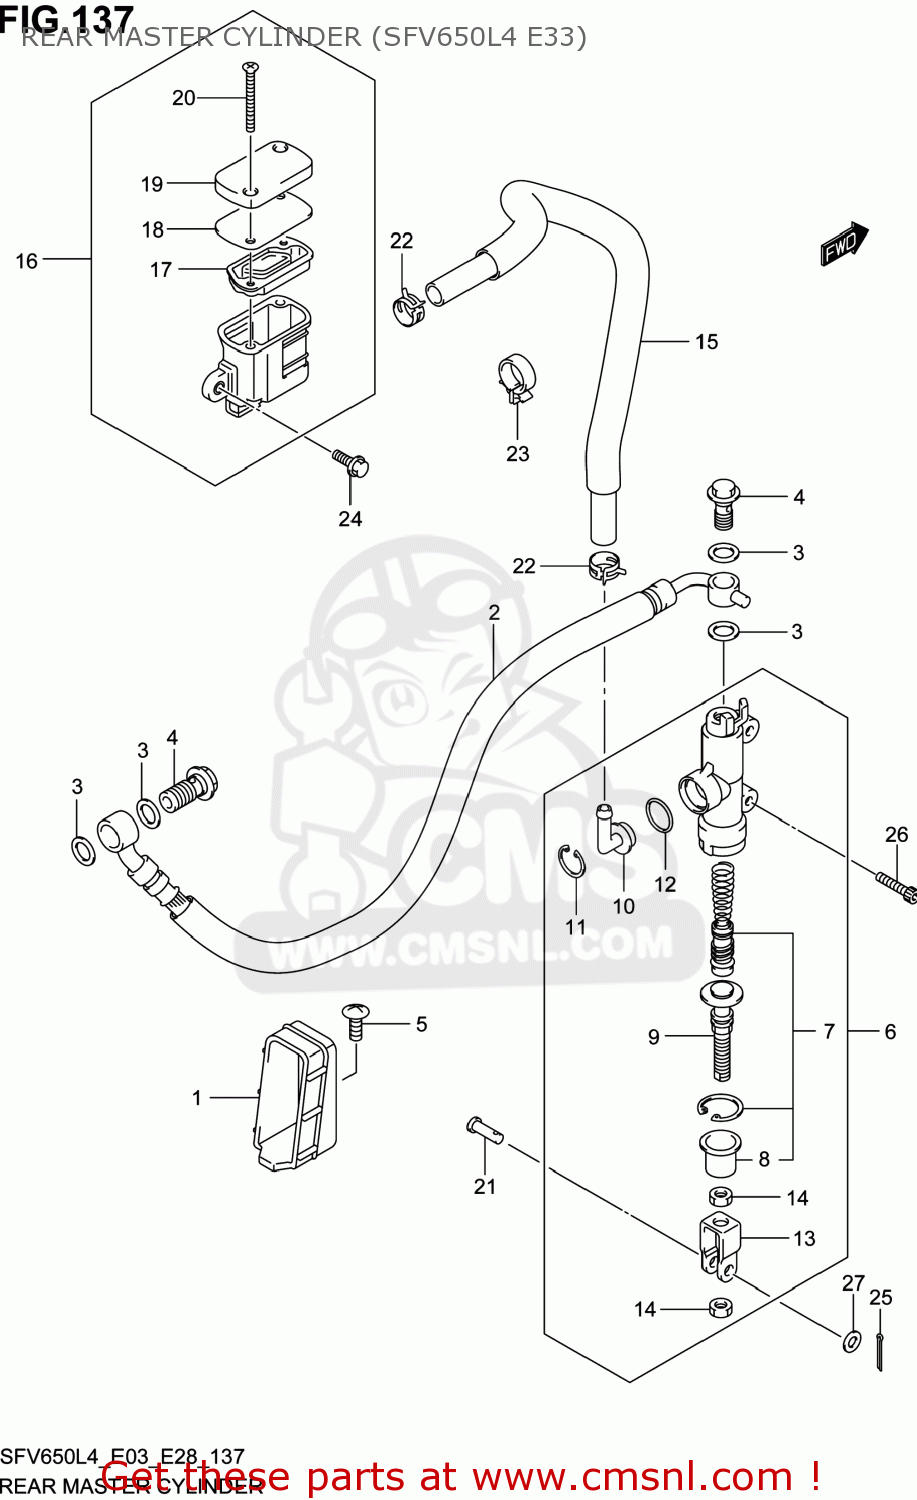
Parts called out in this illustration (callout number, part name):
1	GUIDE,RR BRAKE HOSE
2	HOSE,RR BRAKE
3	WASHER(10X15X1.5)
4	BOLT UNION
5	SCREW
6	CYLINDER ASSY,RR MASTER
7	PISTON/CUP SET
8	BOOT
9	ROD,PUSH
10	CONNECTOR
11	CIRCLIP
12	O RING
13	YOKE
14	NUT
15	HOSE,RR RESERVOIR TANK
16	TANK ASSY,RESERVOIR
17	DIAPHRAGM
18	PLATE,DIAPHRAGM
19	CAP
20	SCREW
21	PIN(6X18.2)
22	CLIP
23	CLAMP
24	BOLT
25	PIN
26	BOLT
27	WASHER
